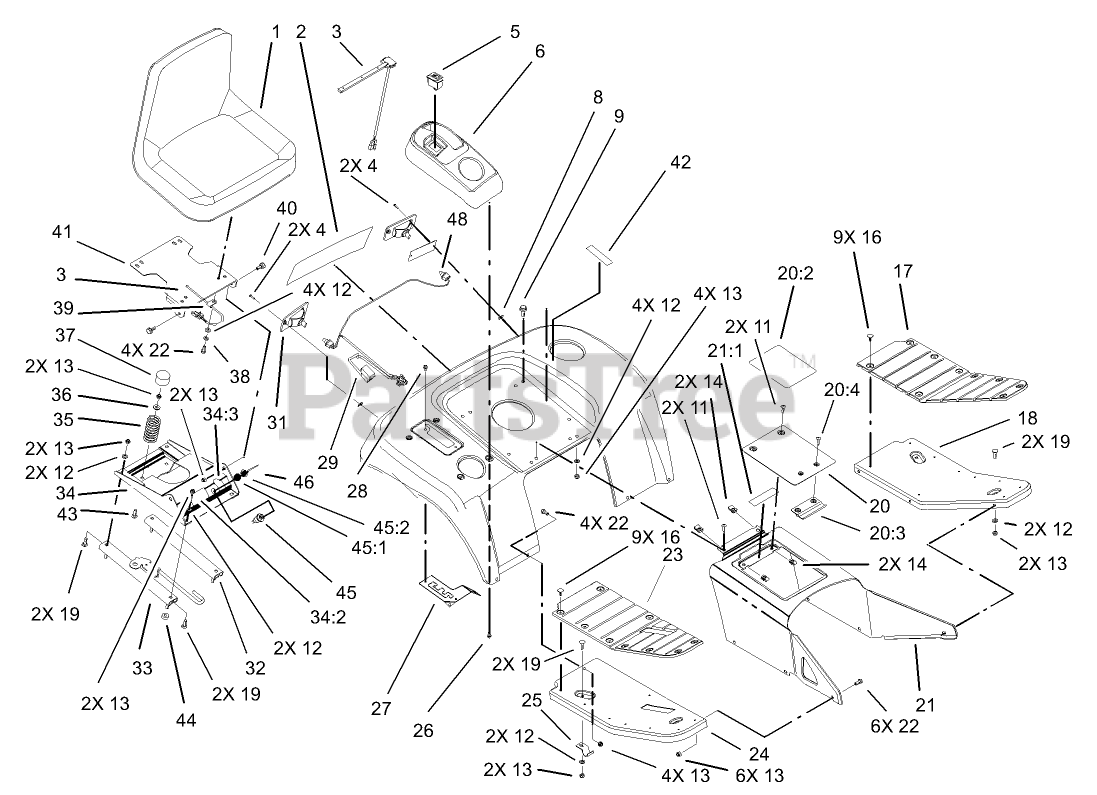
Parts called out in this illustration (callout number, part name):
3	SWITCH-SEAT
4	SCREW-PPH
5	SWITCH-CRUISE
6	POD - CONTROL INT'L
8	NUT-SPEED
9	SCREW-HHF
11	SCREW-HH
12	WASHER-PLAIN
13	NUT-LOCK, NI
16	FASTENER-PANEL
17	PAD-FOOTREST, LH
18	FOOTREST-LH
19	SCREW-CARR
20	TUNNEL COVER ASM
20:2	DECAL - DANGER
20:3	RETAINER-COVER
20:4	SCREW-PPH
21	TUNNEL ASM
21:1	DECAL - WARNING
22	SCREW-HH
24	FOOTREST-RH
25	BRACKET-FOOTREST
26	SCREW-HWH
27	GATE-HI / LO SHIFT
28	SCREW-HWH
29	HARNESS-REAR
31	LAMP-TAILLIGHT
32	SLIDE-SLAVE, SEAT
33	SLIDE-LATCH, SEAT
34:2	DECAL-DANGER
34:3	DECAL-SWITCH
35	SPRING-COMPRESSION
36	BUSHING
37	CAP-SPRING, SEAT
38	WASHER-LOCK
39	CLAMP-R
40	BOLT-SHOULDER,HFH
42	DECAL - DIESEL
43	SCREW-CARR
44	WASHER-FLAT
45	STARTER SWITCH ASM
45:1	WASHER-LOCK
45:2	NUT-HH
46	KEY-IGNITION
48	LIGHT BULB
